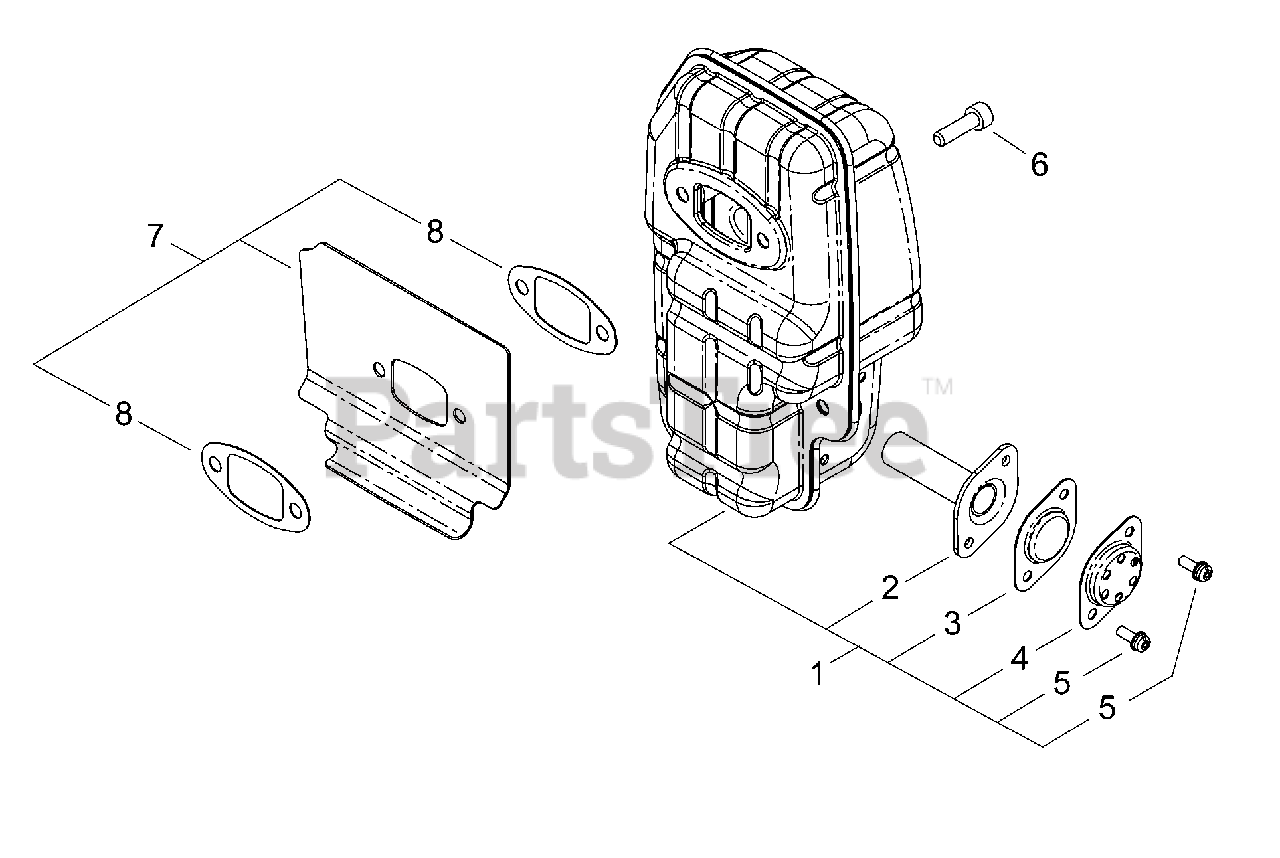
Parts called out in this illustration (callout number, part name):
1	MUFFLER ASSY
2	PIPE, EXHAUST
3	SCREEN, SPARK ARRESTOR
4	GUIDE, EXHAUST
5	SCREW - 4X12
6	SCREW - 6X20
7	EXHAUST SHIELD KIT
8	HEAT DEFLECTOR GASKET
